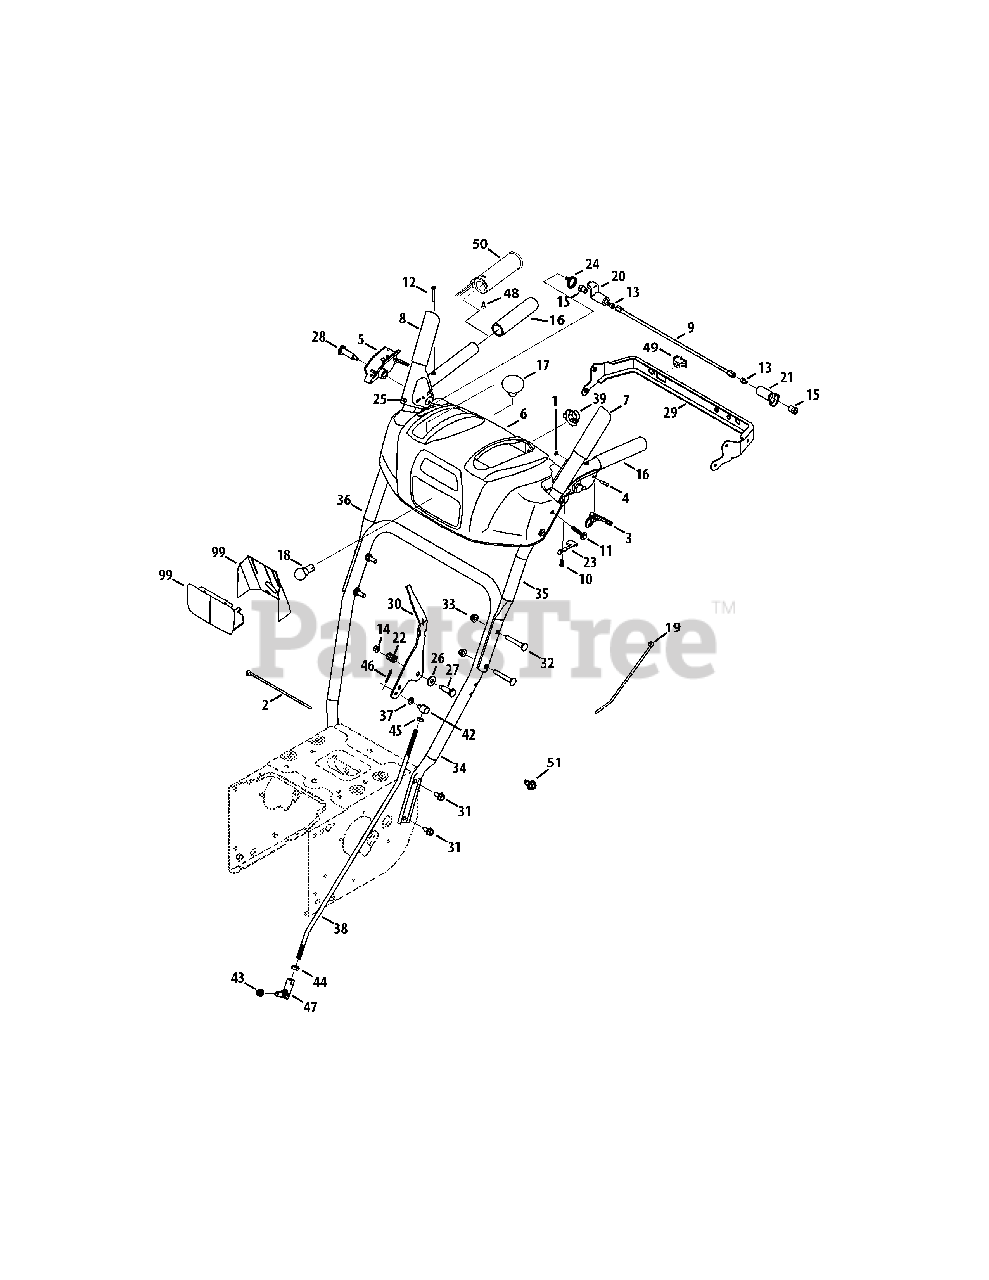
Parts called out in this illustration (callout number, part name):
2	Cable Tie
3	Clutch Trigger
5	Handle Clutch Lock LH Assy
5	Handle Clutch Lock RH Assy
6	Handle Panel, includes Ref. 40 & 41
7	Handle Engagement Assembly LH
8	Handle Engagement Assembly RH
10	Screw, 8-16 x 0.50
11	Screw, 1/4-20 x 1.625
12	Screw, 10-24 x 1.375
13	Socket Screw, 1/4-20 x .50
14	Flange Lock Nut, 1/4-20
15	Shoulder Nut, 1/4-20
16	Handle Grip
17	Shift Knob
19	Cable Tie
21	Clutch Lock Cam
22	Compression Spring
23	Clutch Lock Spring
24	Torsion Spring
25	Rubber Bumper
26	Flat Washer, .385 x .87 x .06
27	Shoulder Screw, .374 x 1.05
28	Shoulder Screw, 1/4-20 x 1.345
30	Shift Lever
31	Hex Screw, 5/16-18 x .750
32	Carriage Screw, 5/16-18 x 2.00
33	Nut, Flangelock, 5/16-18
34	Lower Handle
35	Upper Handle LH
36	Upper Handle RH
37	Flat Washer, .320 x .600 x .060
38	Shift Rod, .343 OD
39	Light Socket
42	Ferrule, 5/16-18 x .312 Dia
43	Jam Lock Nut, 3/8-24
44	Jam Nut, 3/8-24
45	Nut, Jam 5/16-18
46	Bow-Tie Cotter Pin
47	Ball Joint
48	AB Screw, #10-16 x .625 (3X 30" HD)
49	Heated Grip Switch (3X 30" HD)
50	Heated Grip (3X 30" HD)
51	Screw, TT, 1/4-20 x .500 (For ground wire)
99	Lens Label
